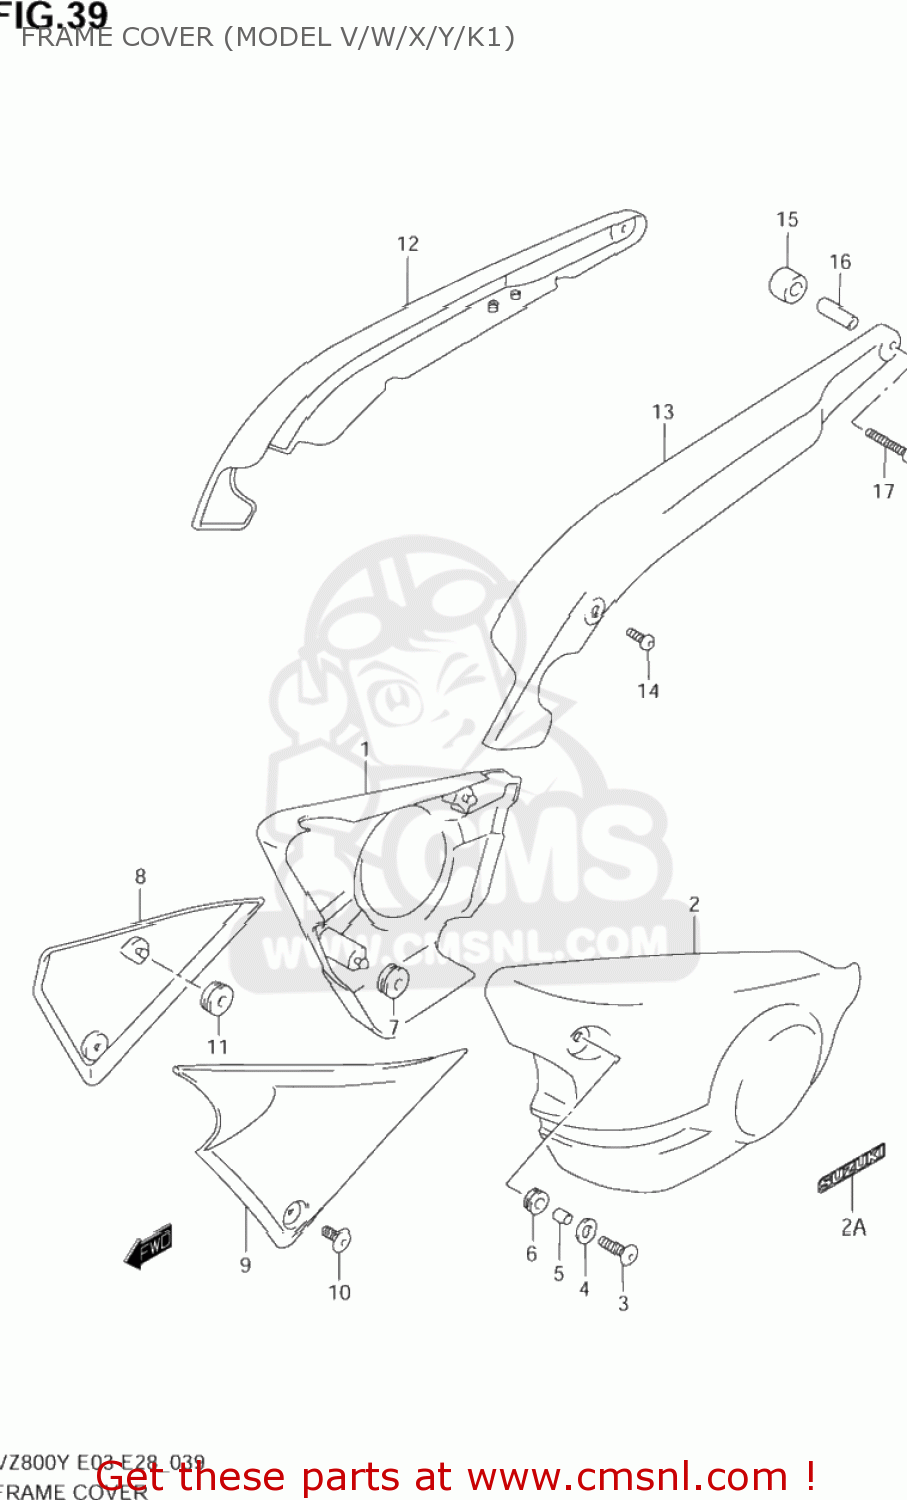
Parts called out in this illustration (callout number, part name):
1	COVER,FRAME,RIGHT
2	COVER,FRAME,L
2A	EMBLEM,FRAME COVER CTR
3	SCREW(6X16)
4	WASHER(6.5X18X1)
5	SPACER(6.5X9X9)
6	CUSHION
7	CUSHION
8	COVER,FRAME HEAD,R
9	COVER,FRAME HEAD,L
10	SCREW(6X16)
11	CUSHION
12	COVER,FRAME RR,R
13	COVER,FRAME RR,L
14	BOLT(8X16)
15	CUSHION,FRAME RR COVER RR
16	SPACER(8.5X12X23.5)
17	BOLT
